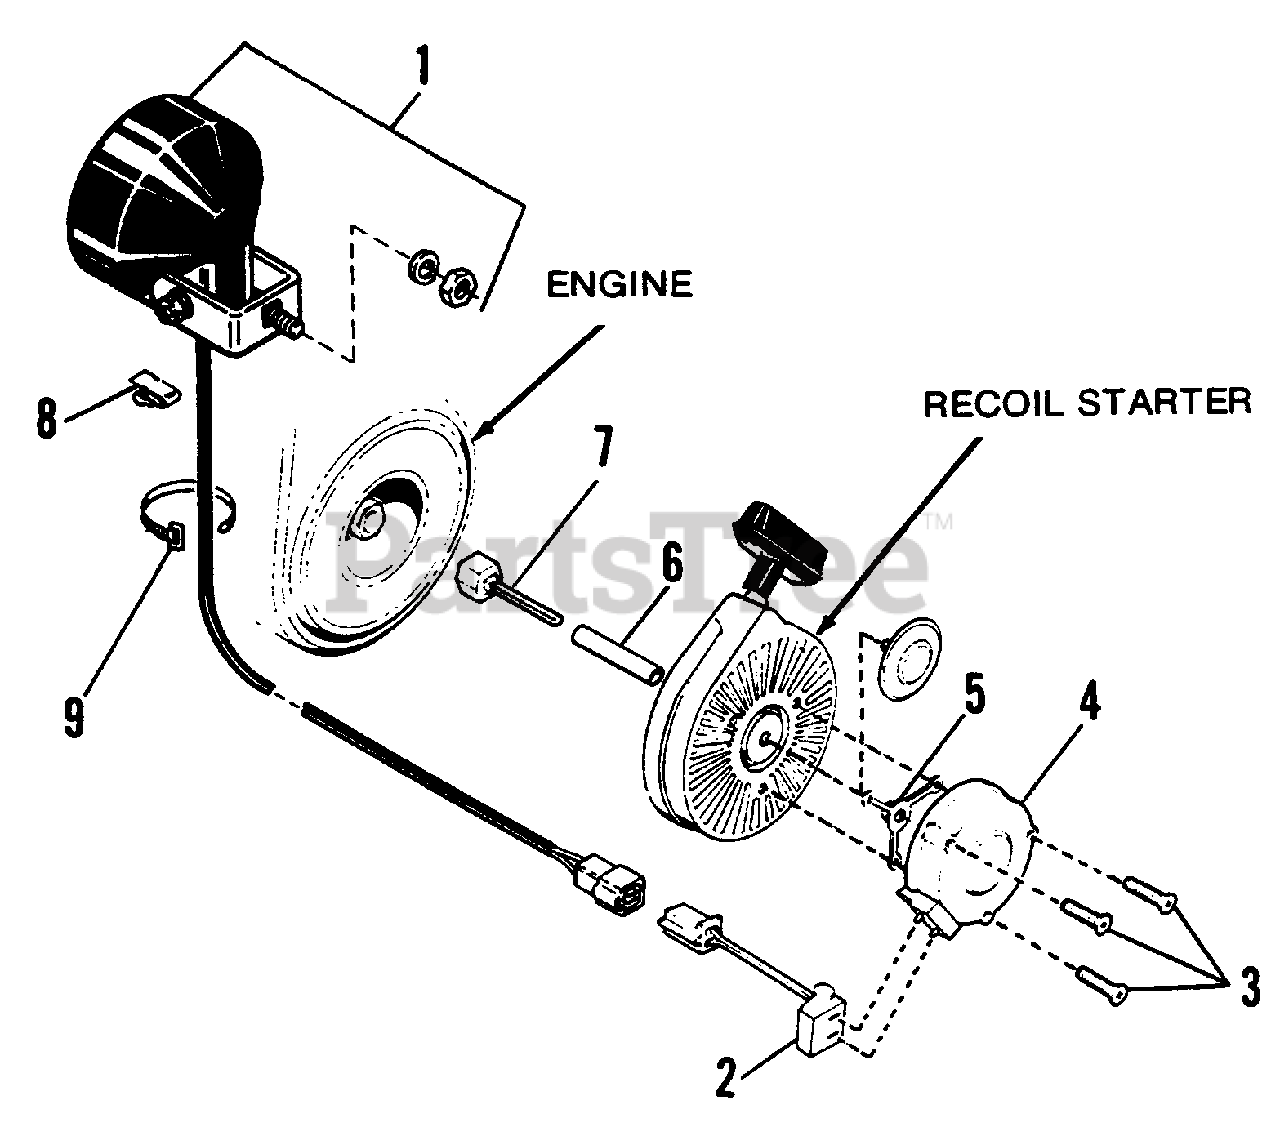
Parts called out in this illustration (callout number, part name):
1	LIGHT, Add-On
2	CONNECTOR, A-C Lighting
3	SCREW, Self-Tapping, 1-1/4"
3	SCREW, Self-Tapping, 1-1/8"
4	ALTERNATOR
5	SPACER
6	TUBE, Centering
7	SHAFT, Alternator, 3-1/2"
7	SHAFT, Alternator, 3"
